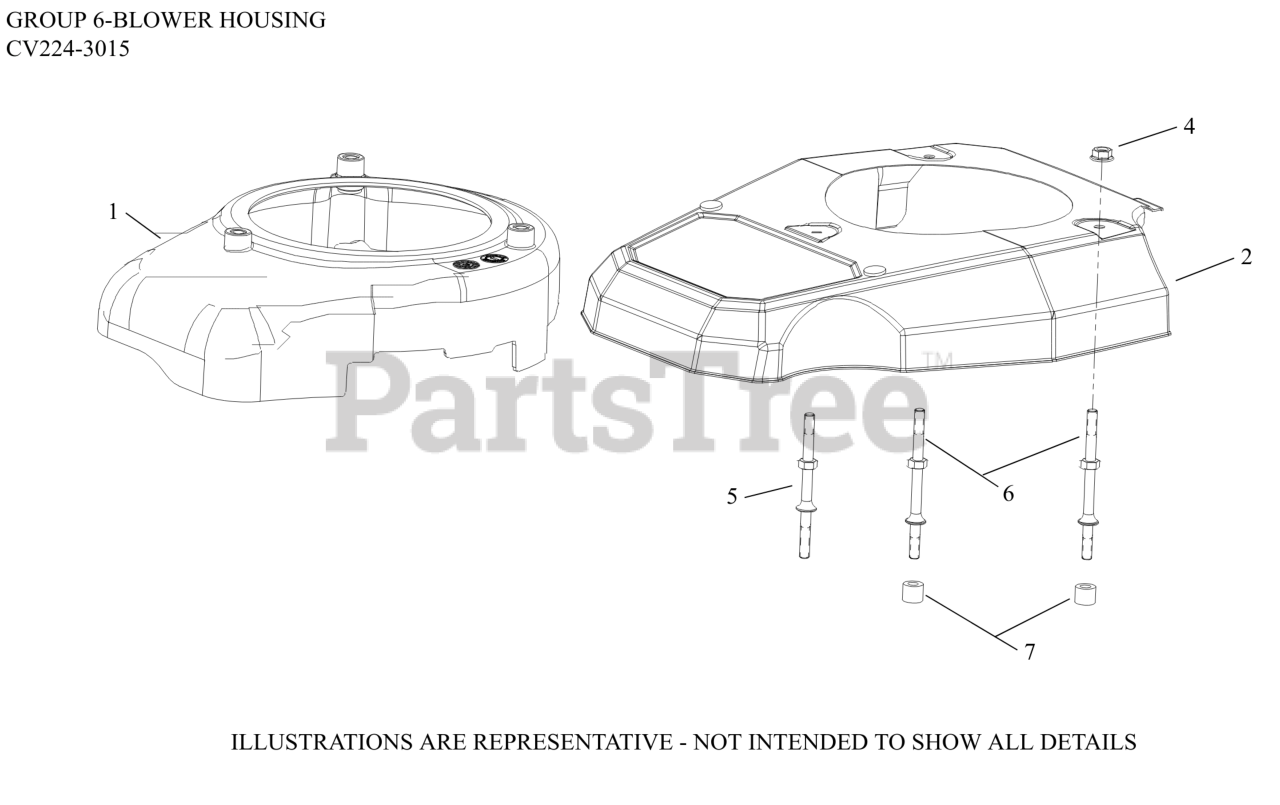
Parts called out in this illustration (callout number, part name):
1	KIT, BLOWER HOUSING
2	COVER, ENGINE
3	COVER, ENGINE
4	NUT, HEX FLANGE (M6) - USE 14 100 16-S
5	STUD-USE 14 072 25-S
6	STUD, BLOWER HOUSING
7	SPACER, BLOWER HOUSING
